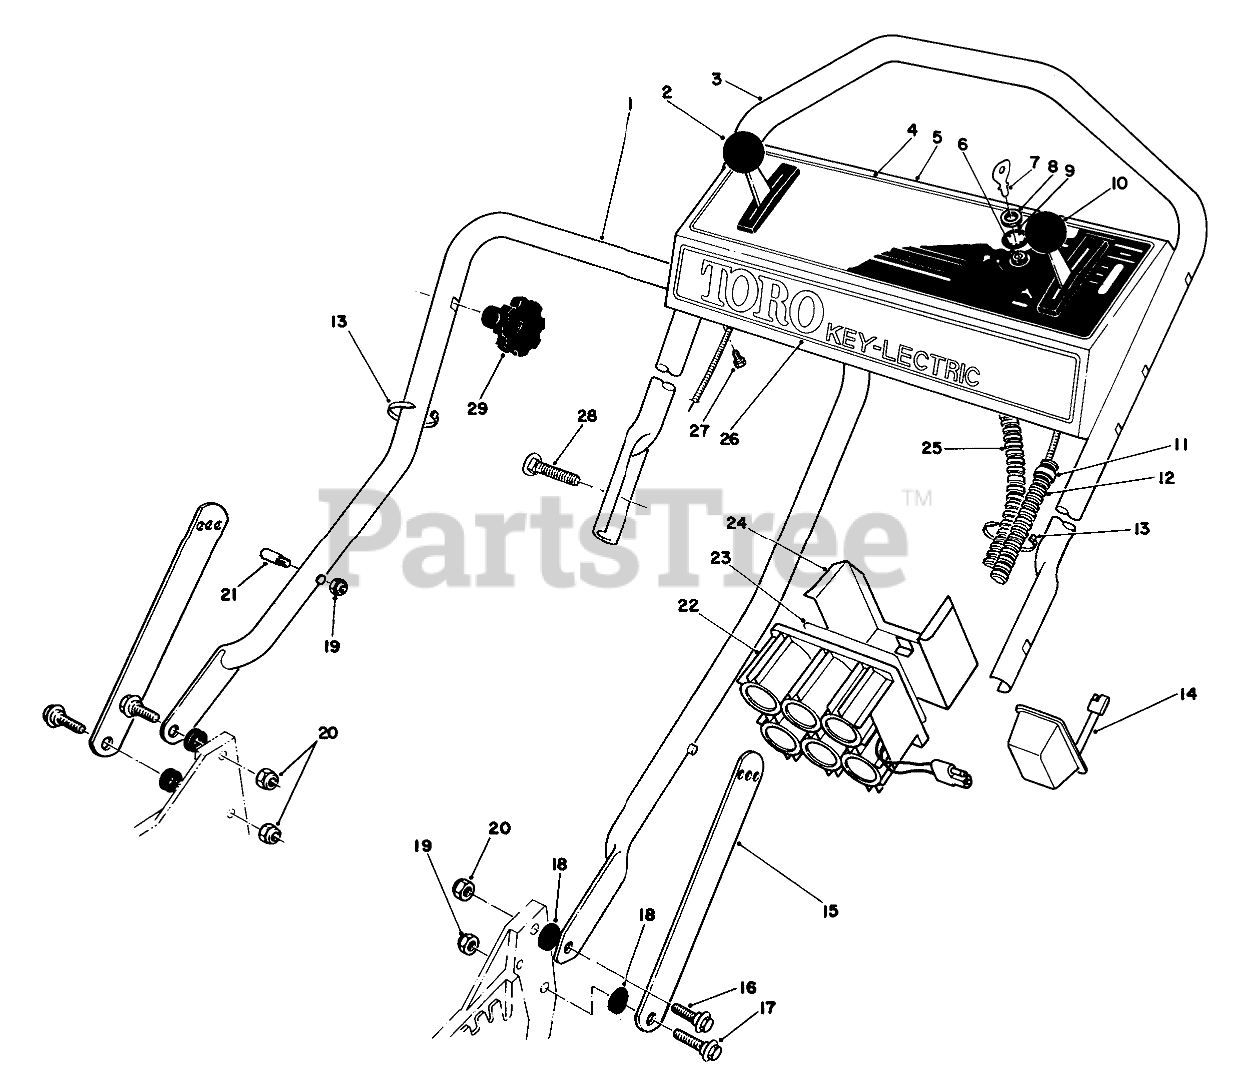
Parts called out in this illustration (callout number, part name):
1	LOWER HANDLE ASM
2	GROUND SPEED CONTROL
3	Handle-Upper
4	OBS INSTR PANEL DECAL
5	Control Panel (Incl. Ref. #4)
6	Switch-Starter (Incl. Ref. #8-9)
7	Key
8	NUT-HH
9	WASHER-TOOTH, INTERNAL
10	SERVICE THROTTLE CONTRO
11	FITTING-RING
12	CONTROL CABLE COVER
13	TIE-CABLE
14	Charger
15	Handle Latch
16	SCREW-SHOULDER
17	SCREW-SHOULDER
18	SPACER
19	NUT-LOCK, NI
20	NUT-LOCK, NI
21	HANDLE PIN
22	BATTERY ASSEMBLY
23	Decal
24	Retainer-Battery
25	WIRE HARNESS
26	Decal-Toro
27	SCREW-HWHTF
28	5/16-18 X 2 HNDLE SCREW
